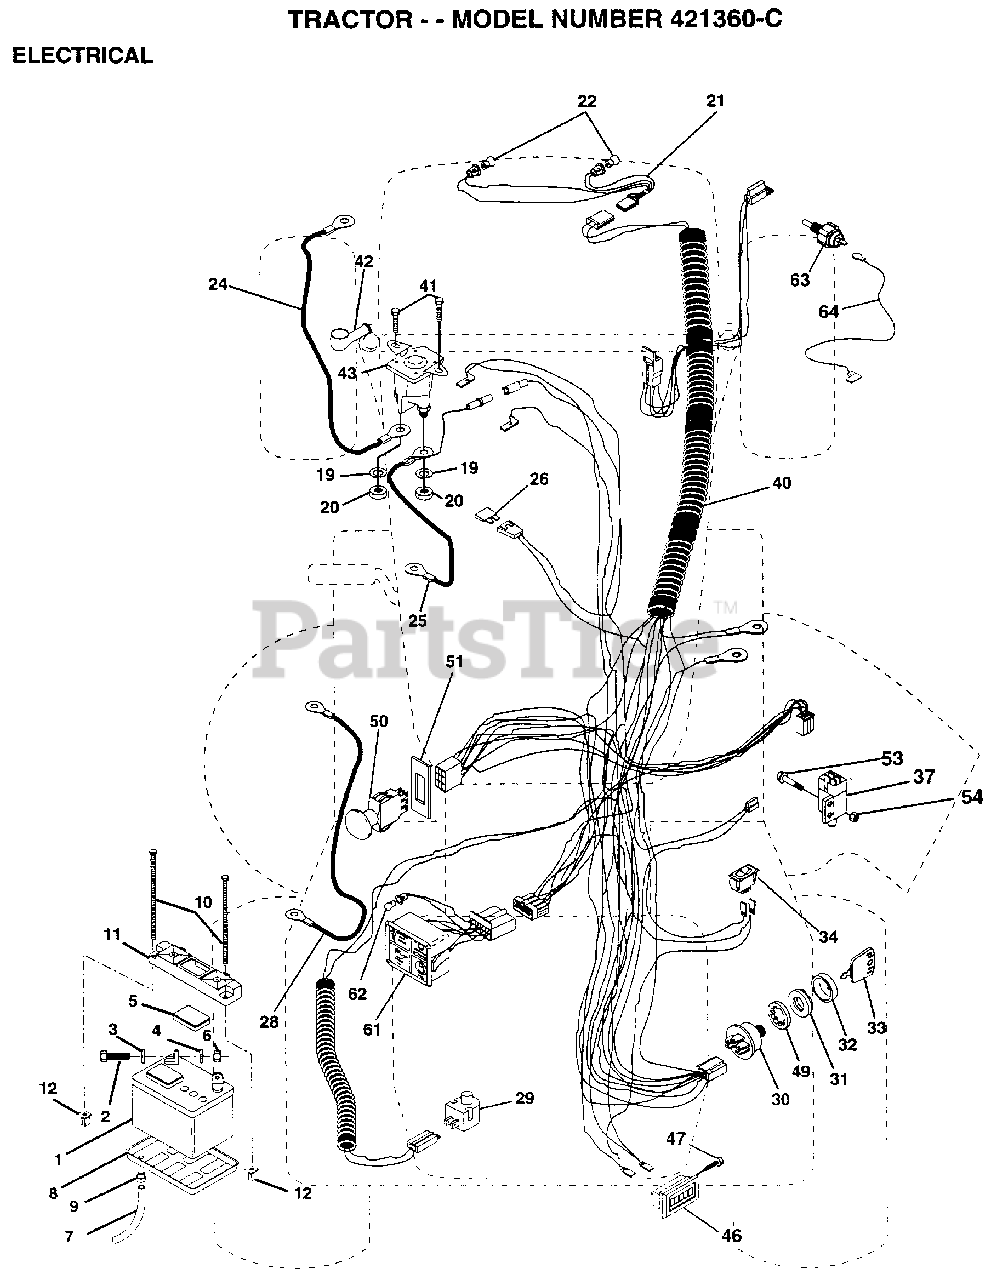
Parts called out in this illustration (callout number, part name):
1	DRY BATTERY 35AMP
2	BOLT LT
3	LOCKWASHER
4	WASHER
5	"CAP,BATTERY "
7	"DRAIN TU T, BATT"
8	"TRAY T, BATTERY"
9	HOSE CLAMP T
20	NUT
21	"HARNESS,LIGHT SOC"
22	HEADLAMP BULB
24	CABLE.BATY.22.RED
25	CABLE.BATRY.4GA.
26	FUSE HYT
28	CABLE.BATRY.4GA.
29	SWITCH SEAT
32	COVER KEY SWITCH
33	KEY MLD GEN DELTA
34	SWITCH LT
37	SWITCH INTERLOCKT
41	SCREW
46	HOUR METER T
47	SCREW
49	LOCKWASHER
51	RING RETAIN PTO
53	SCREW
54	"NUT,KEPS"
61	LIGHT.PKG.ASM.
62	BULB LIGHT T
